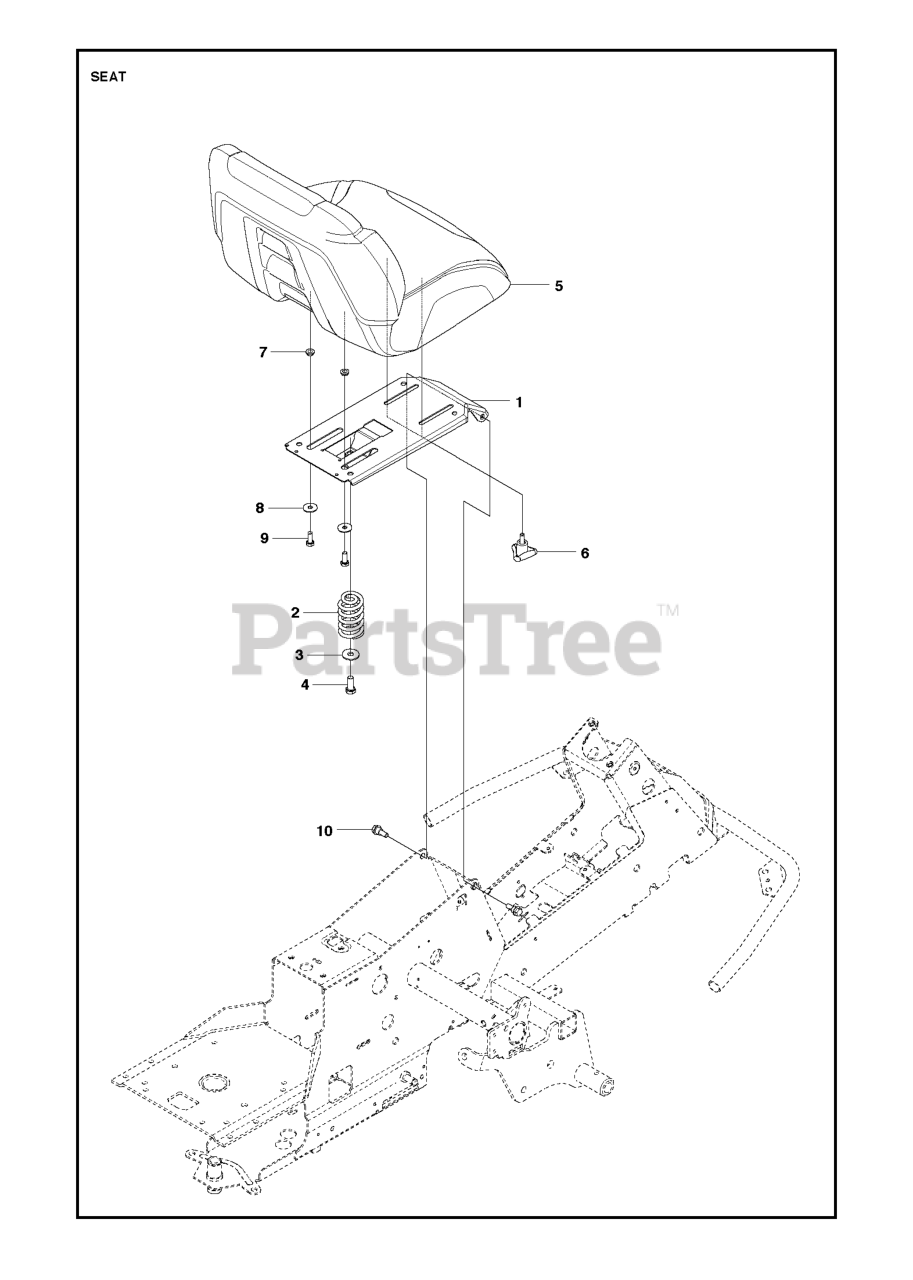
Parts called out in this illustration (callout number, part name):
1	SEAT BRACKET 300 ASSY GREY
2	SEAT SPRING
4	Screw M10x25
5	SEAT HUSQVARNA LOW BACK
